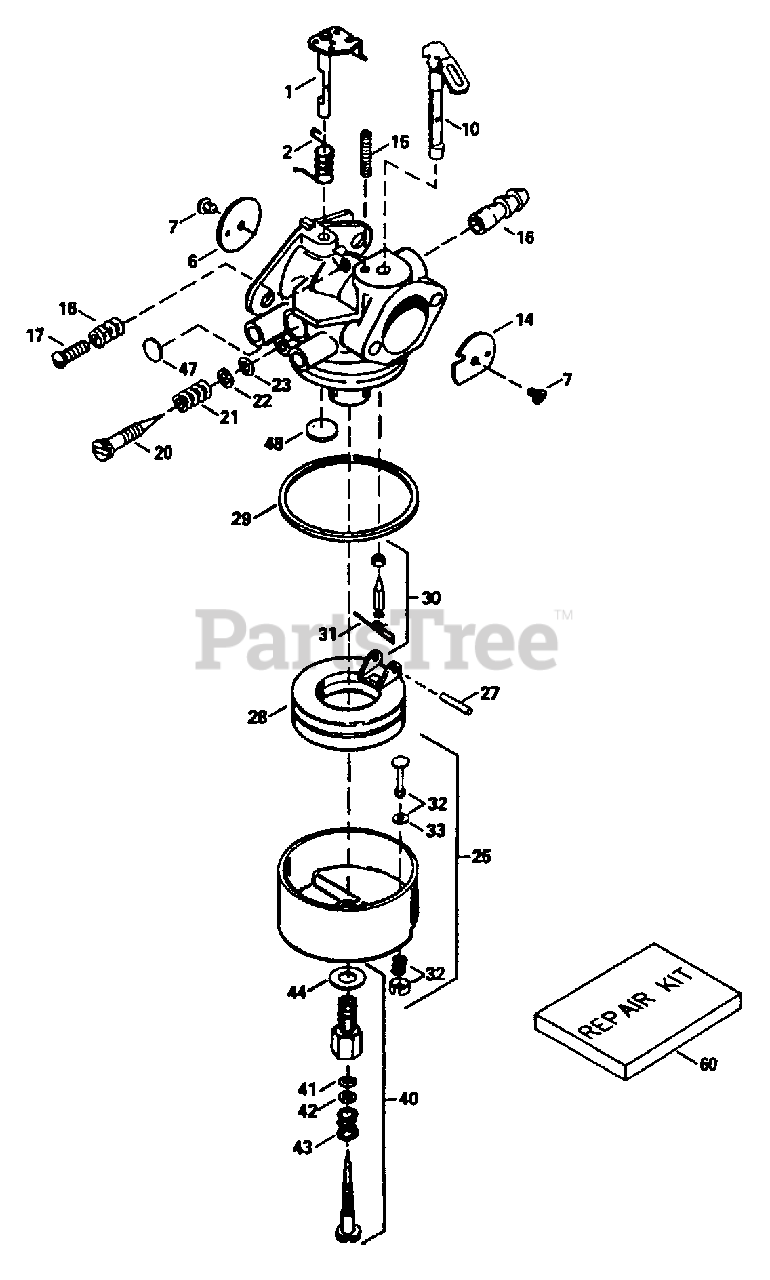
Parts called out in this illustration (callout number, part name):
1	Throttle Shaft & Lever Assy
2	Throttle Return Spring
6	Throttle Shutter
7	Shutter Screw
10	Choke Shaft & Lever Assy
14	Choke Shutter
15	Choke Positioning Spring
16	Fuel Fitting
17	Throttle Crack Screw/Idle Speed Screw
18	Tension Spring
20	Idle Mixture Screw
21	Tension Spring
22	Idle Mixture Screw Washer
23	Idle Mixture Screw "O" Ring
25	Float Bowl Assy
27	Float Shaft
28	Float
29	Float Bowl "O" Ring
30	Inlet Needle, Seat & Clip
31	Spring Clip
32	Bowl Drain Assy
33	Drain Plunger Gasket
40	Main Adj. Screw Assy
41	High Speed Mixture Screw "O" Ring
42	High Speed Mixture Screw Washer
43	High Speed Mixture Screw Tension Spring
44	Bowl Nut Washer
47	Welch Plug, Idle Mixture Well
48	Welch Plug, Atmospheric Vent
60	Repair Kit
